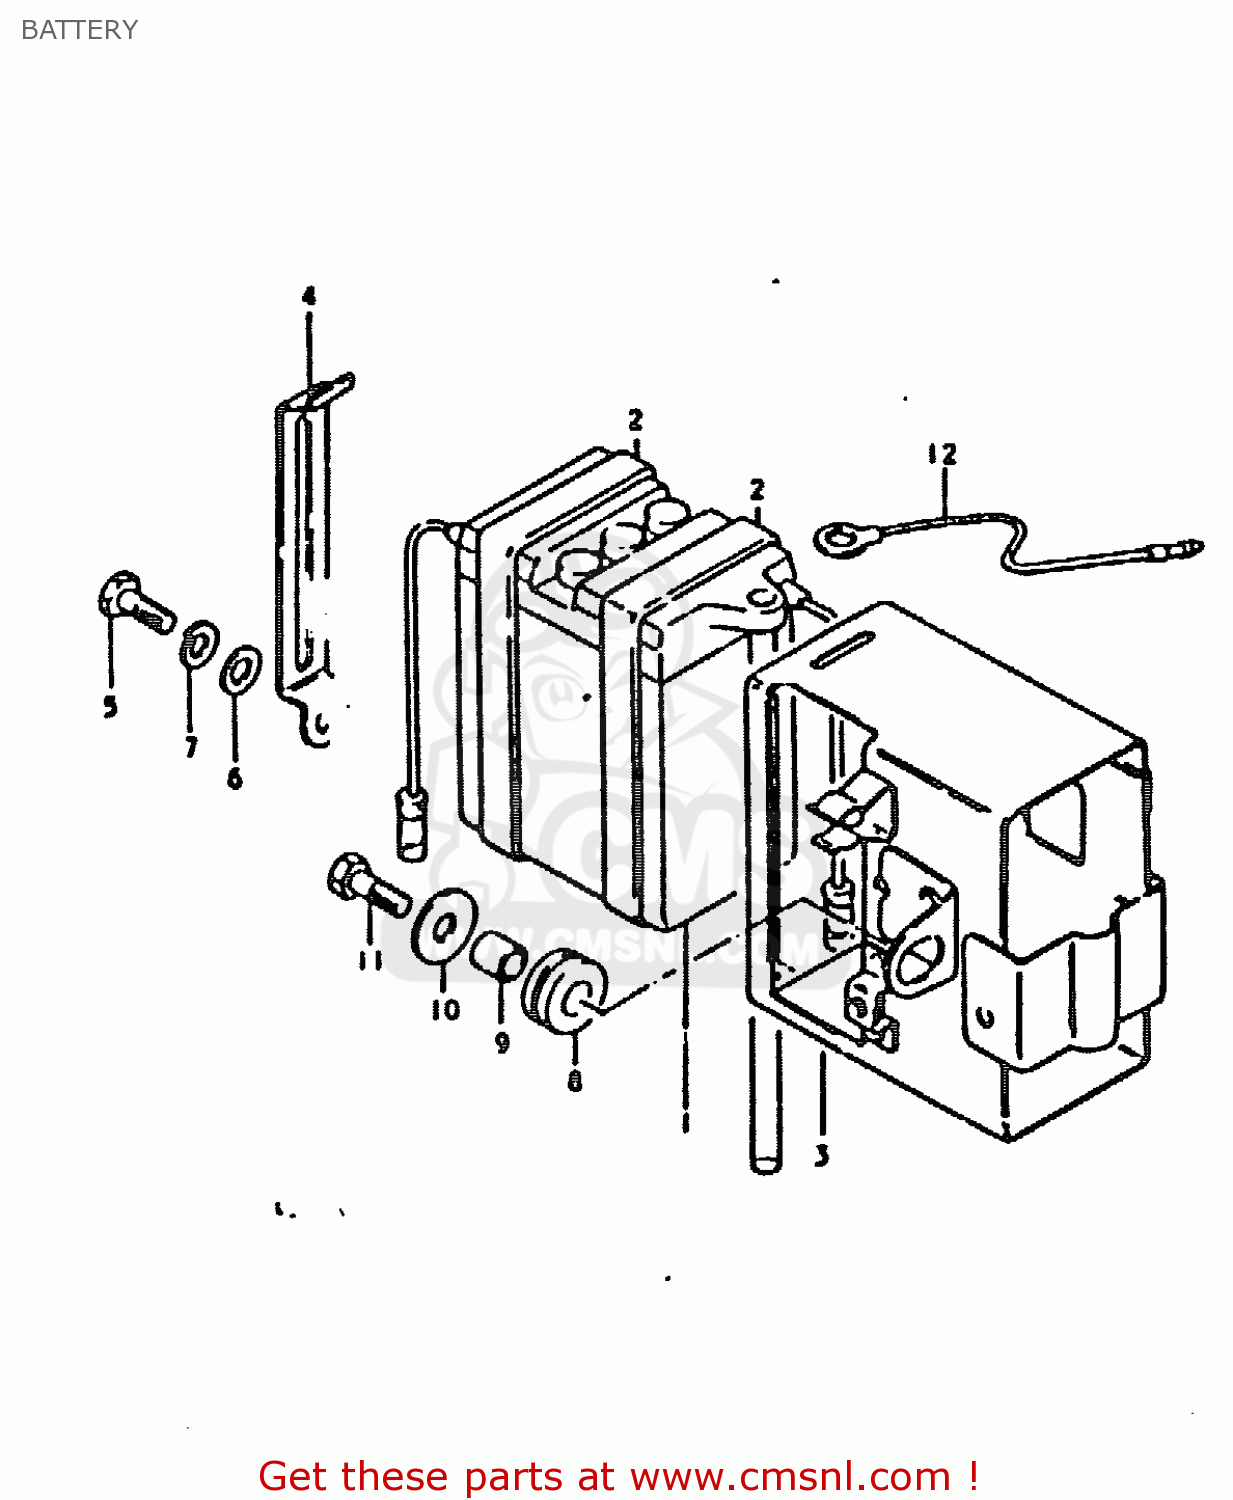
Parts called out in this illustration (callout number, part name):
1	BATTERY(6N4B-2A,6V4.2AH)
2	PROTECTOR,BATTERY
3	HOLDER,BATTERY
4	PLATE, HOLDER
5	SCREW(6X10)
6	WASHER
7	LOCK WASHER
8	CUSHION
9	SPACER (7X9X7)
10	WASHER (6.5X20X1.2)
11	SCREW
12	LEAD WIRE
